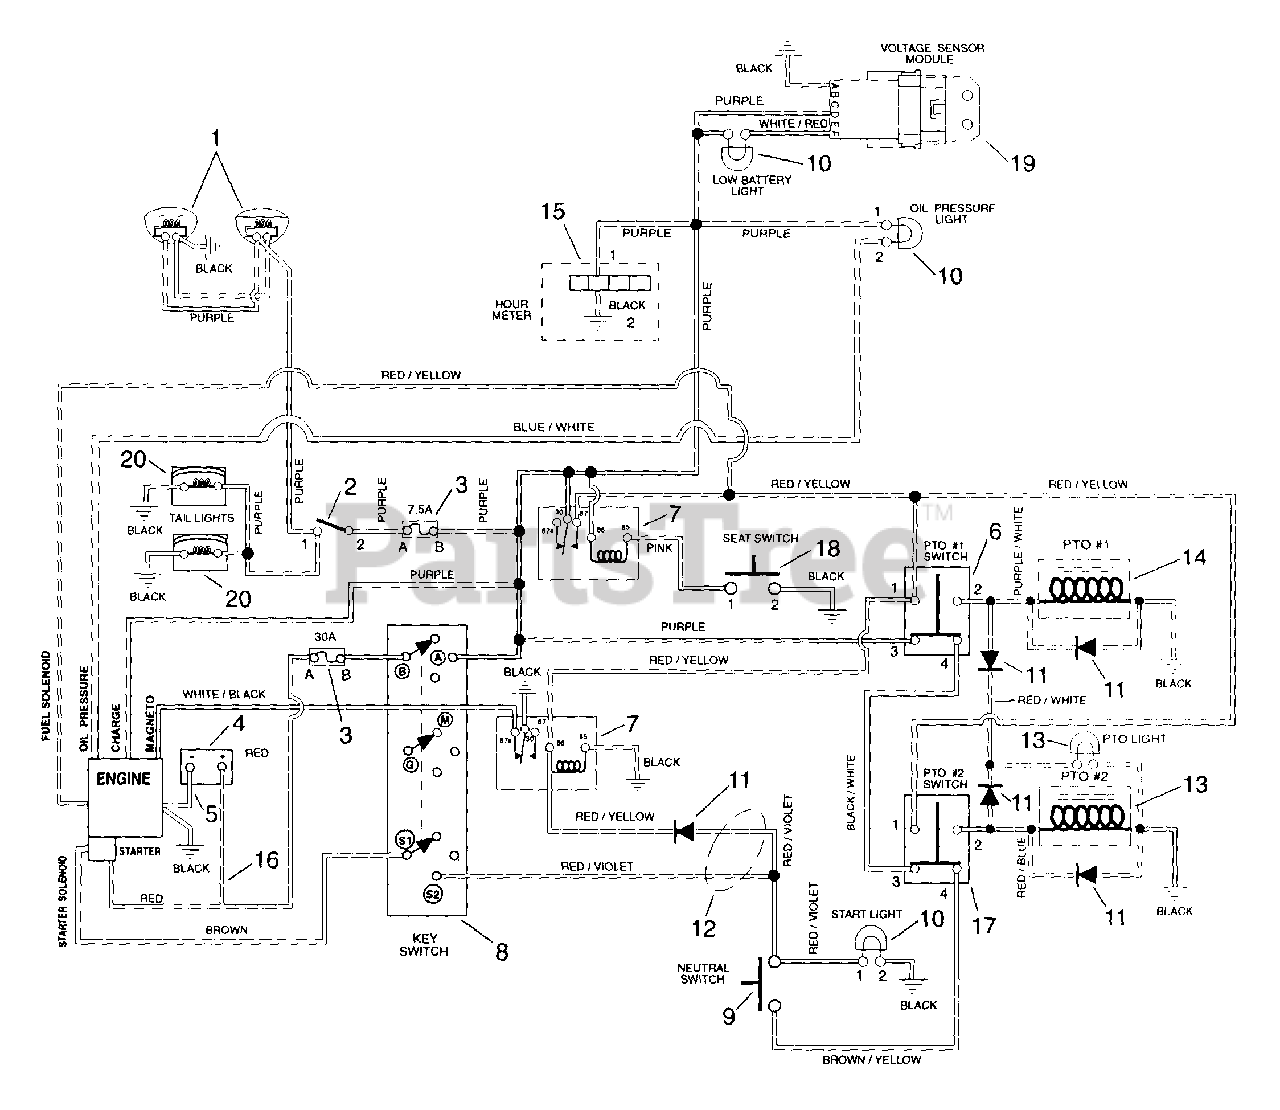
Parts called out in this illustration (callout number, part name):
1	HEADLIGHT- RH
1	HEADLIGHT- LH
2	SWITCH - LIGHT
3	7.5 AMP Fuse
3	30 AMP Fuse
4	BATTERY
5	CBL,NEGATIVE BATTERY 20.00
6	PTO KNOB/ SWITCH ASSY
7	RELAY
8	KEY SWITCH
9	SWITCH- SINGLE POLE N.O.
10	#194 Bulb
11	MOLDED DIODE PLUG 1 AMP
12	WIRE HARNESS- KOHLER V (4-PIN)
13	ELECTRIC CLUTCH
14	CLUTCH-ELEC. WARNER I-5215-62B
15	HOUR METER
16	CBL,BATTERY TO SOLENOID
17	CLUTCH SWITCH
18	SWITCH- SEAT
19	MODULE - VOLTAGE SENSOR
20	TAIL LIGHT ASSEMBLY W/BULLET
